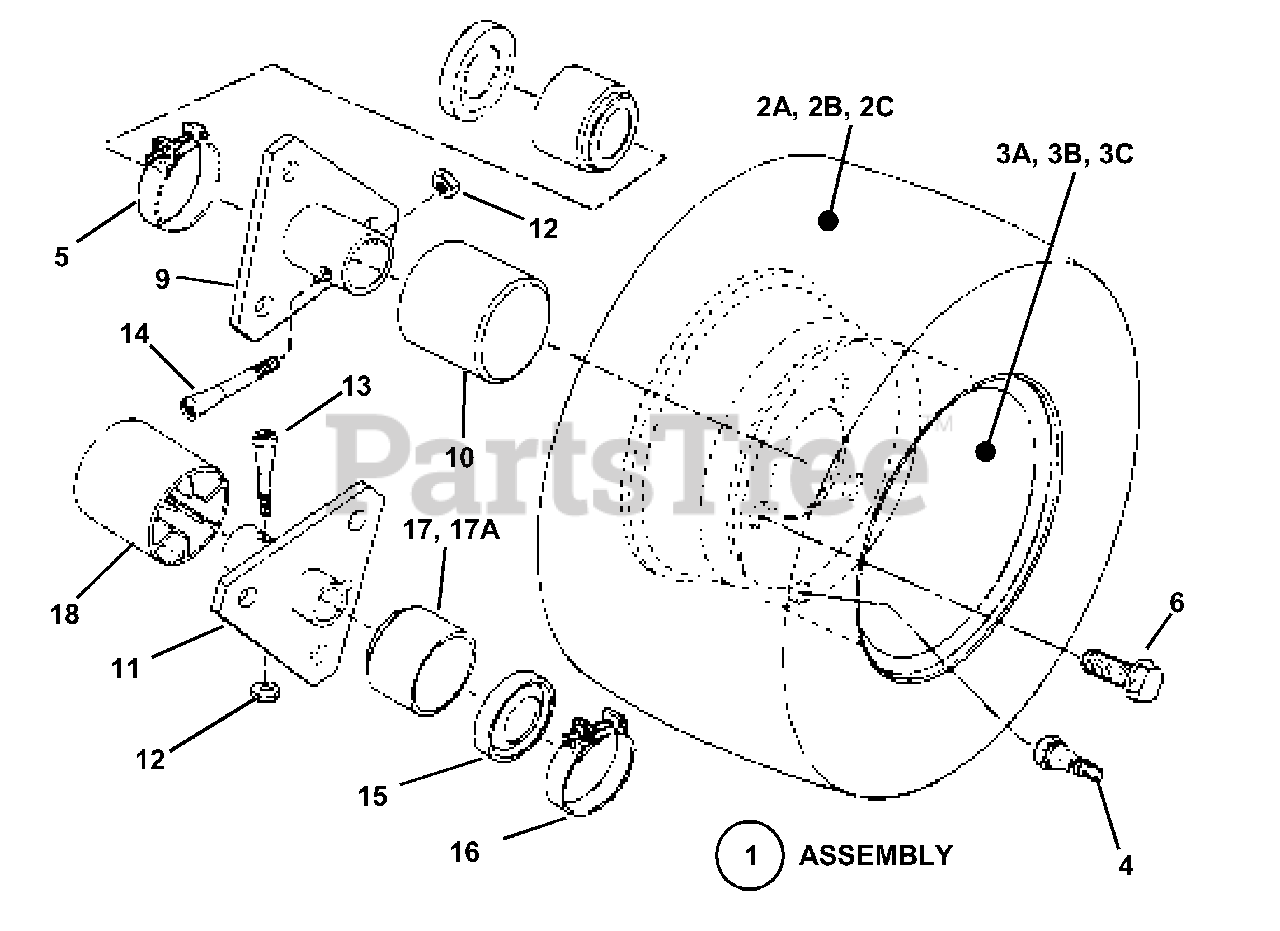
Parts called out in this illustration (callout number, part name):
1	ASSEMBLY, Rear Tire & Rim
2A	TIRE,
2B	TIRE, Wide, 16-6.50 x 8 (28" Models)
2C	TIRE, Extra Wide, 16-7.50 x 8 (33" Models)
3A	RIM,
3B	RIM, Wide,
3C	RIM, Extra Wide,
4	VALVE, Air (Snap-in)
5	CLAMP, Right Hand (8, 10, 12, 13 & 15HP)
6	BOLT, 1/2-20 x 3/4" Lug, Grade 5 (6)
9	HUB, Rear Wheel (Right Hand)
10	CAP, Hub
11	HUB, Rear Wheel
12	NUT, 5/16-24 Hex Center Lock
13	BOLT, 5/16-24 x 1-5/8" Tapered (Left Hand)
14	BOLT, 5/16-24 x 2" Tapered (Right Hand)
15	SEAL, Oil (Left Hand)
16	CLAMP, (Left Hand) (13 & 14 HP)
17	BOOT, Ball Bearing Models (Left Hand) (13 14 & 15HP Engines)
17A	BOOT, Standard Models (Left Hand) (8, 10, 12 & 13HP Engines)
18	CAP, Hub (Left Hand)
